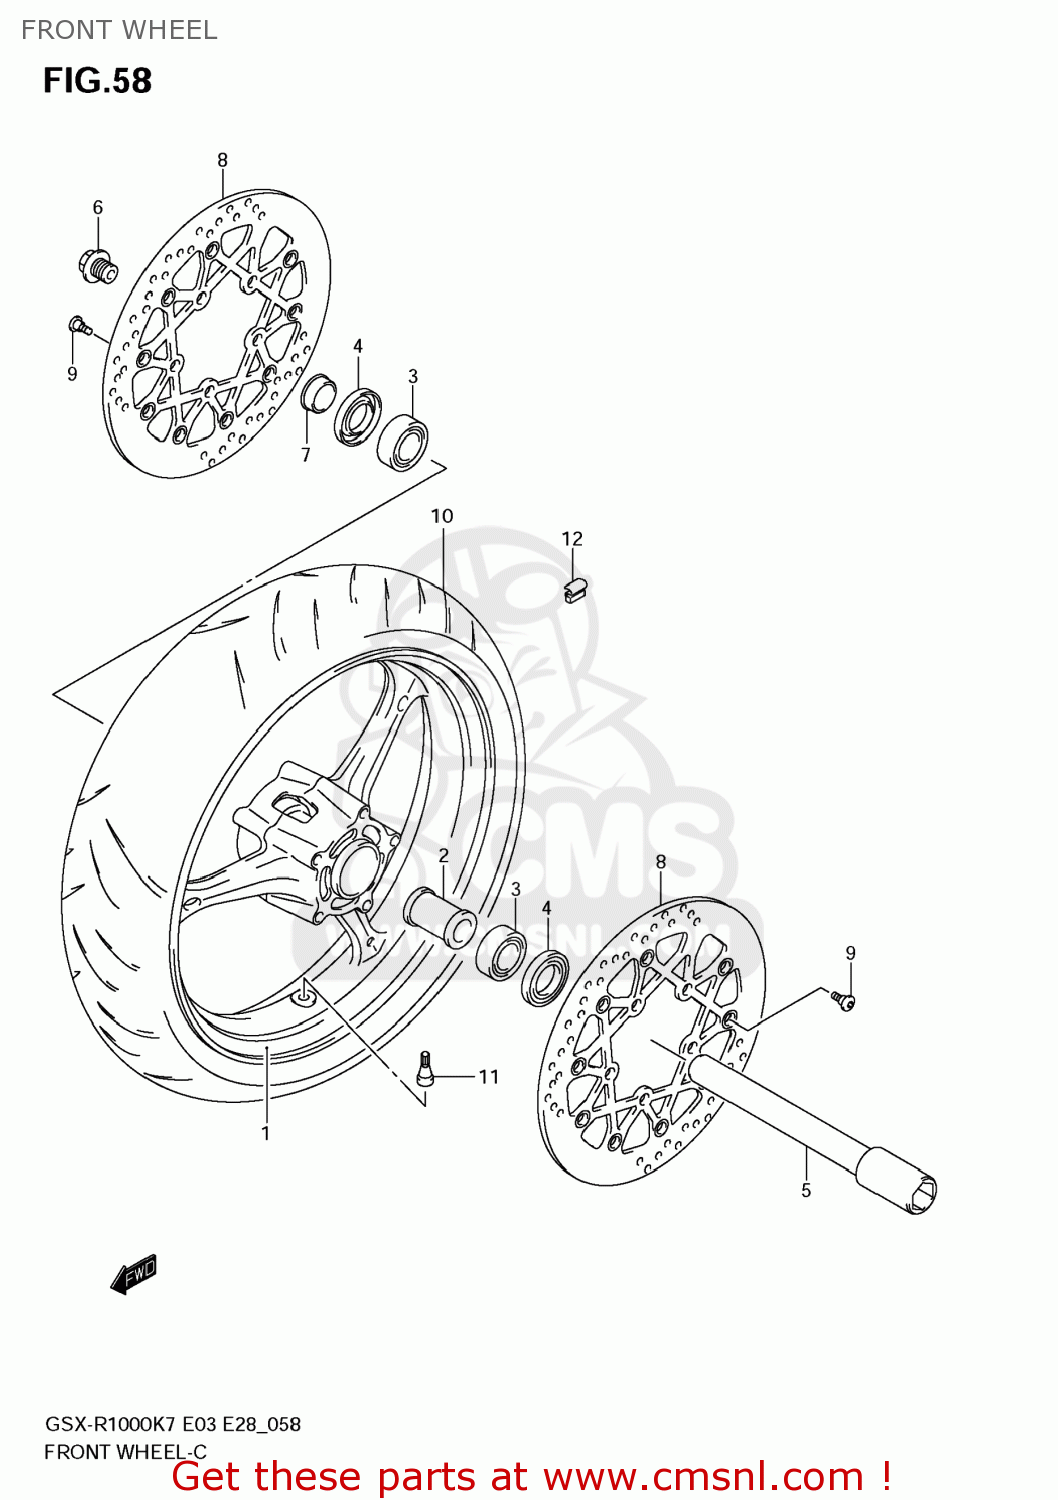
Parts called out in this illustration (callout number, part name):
1	WHEEL,FR(17M/CXMT3.50)
2	SPACER,FR HUB BEARING
3	BEARING(25X52X15)
4	SEAL,OIL(32X52X7)
5	AXLE,FR
6	BOLT,FRONT AXL
7	SPACER,FRONT A
8	DISC,FR BRAKE
9	BOLT(8X21)
10	TIRE,FR
11	VALVE ASSY,WHEEL RIM(TR412)
12	BALANCER,WHEEL NO.1
